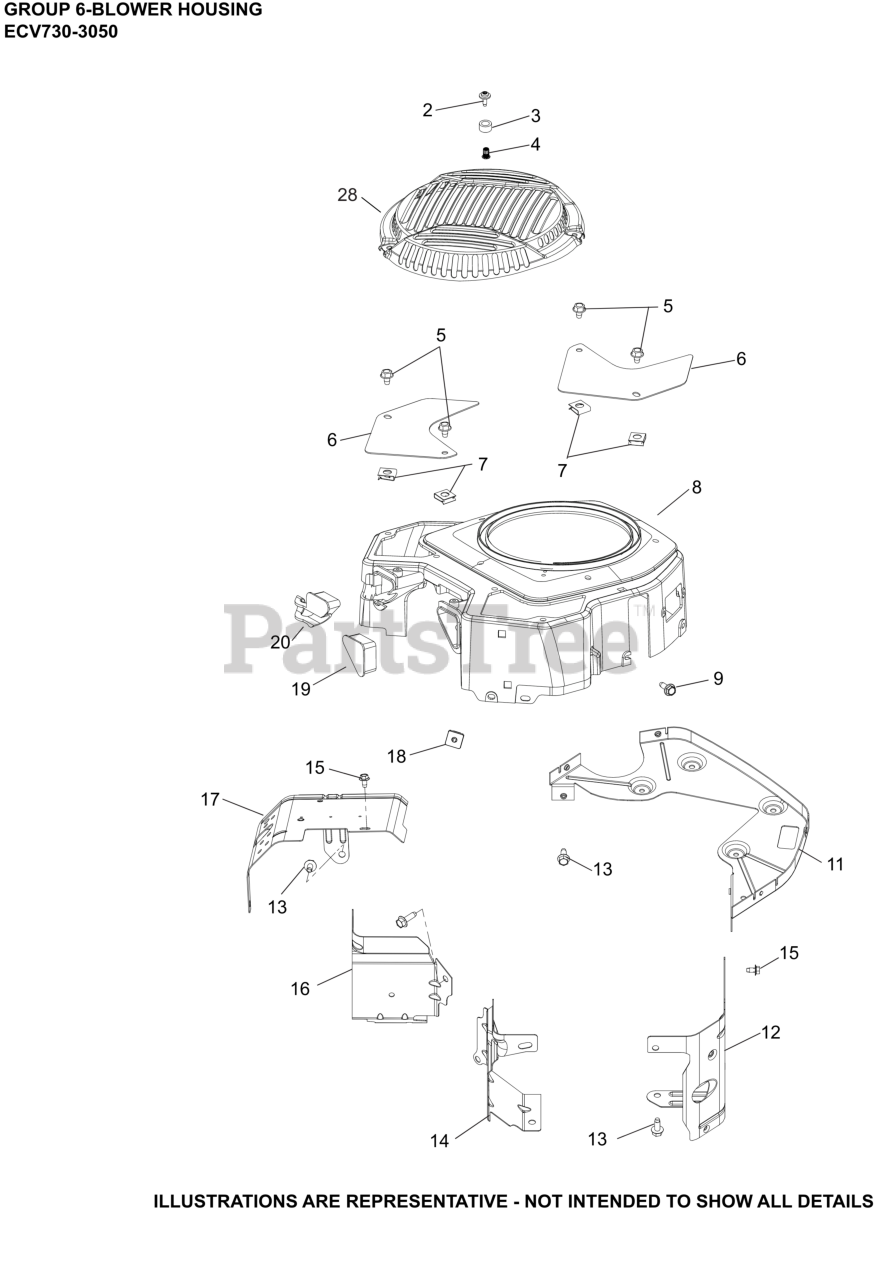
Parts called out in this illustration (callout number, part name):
2	SCREW, SEMS
4	INSERT, THREADED (M5)
5	SCREW, THREAD FORMING
6	KIT, ACCESS PANEL
7	CLIP, BAFFLE MOUNTING
8	HOUSING, BLOWER
9	SCREW, THREAD FORMING
11	PLATE, BACKING
11	KIT, BACKING PLATE
12	BAFFLE LEFT BARREL
13	SCREW, THREAD FORMING
14	BAFFLE, VALLEY #2 CYLINDER
15	SCREW, THREAD FORMING
16	BAFFLE, VALLEY #1 CYLINDER
17	KIT, RIGHT BARREL
18	NUT, PLASTIC
19	COVER, BLOWER HOUSING
20	COVER, BLOWER HOUSING
28	GUARD, GRASS SCREEN (METAL)
NI	STRAP, LIFTING
